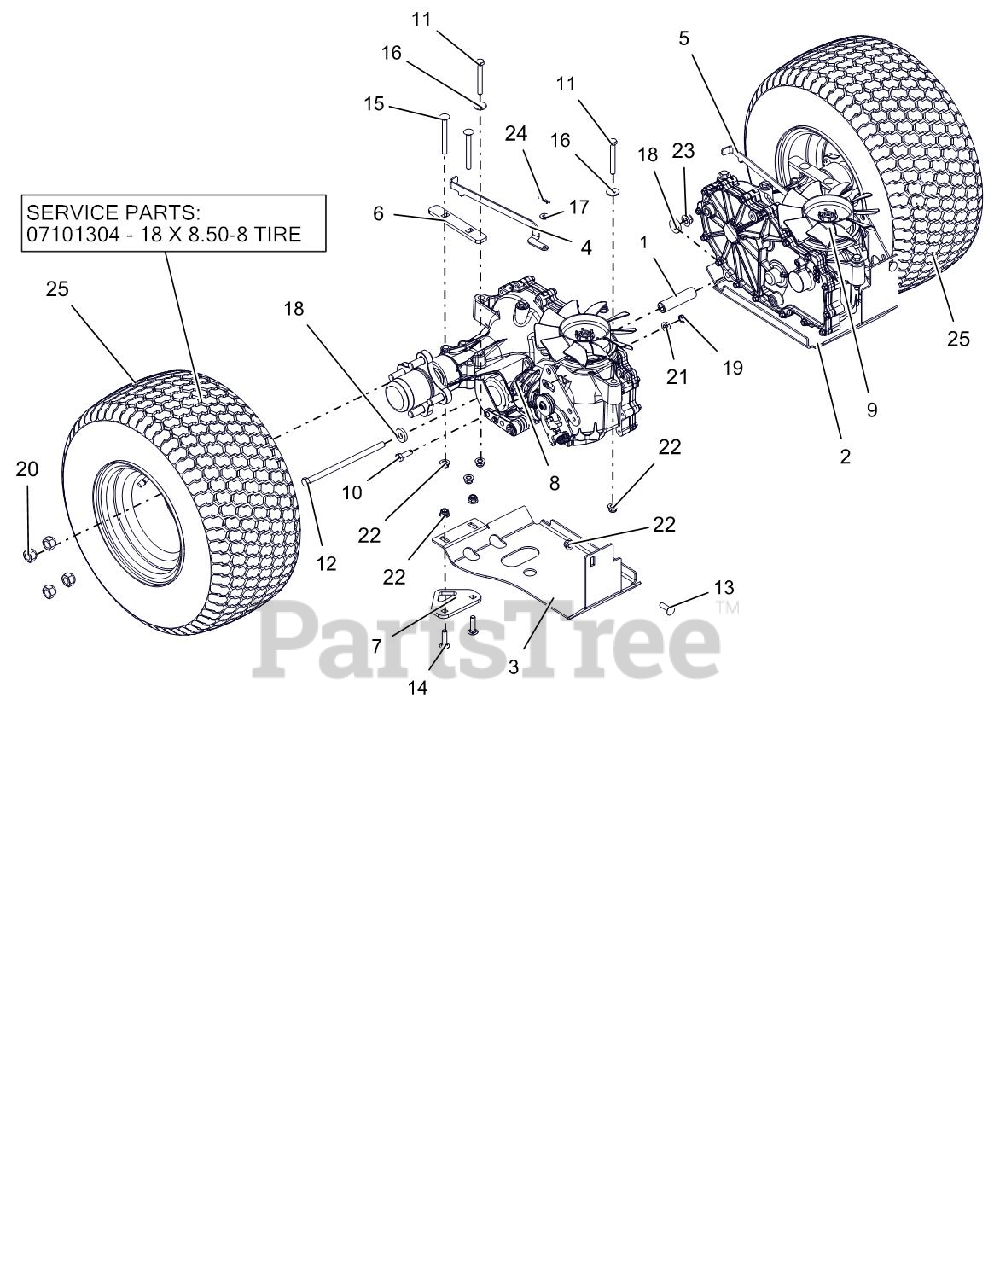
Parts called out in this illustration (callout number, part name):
1	SHAFT, CROSS BRACE
2	PLATE, TRANS SKID
3	PLATE, TRANS SKID
4	BRKT, LH DUMP VALVE
5	BRKT, RH DUMP VALVE
6	DOUBLER, TRANS MNT
7	BRKT, TIE DOWN LOOP
8	TRANSAXLE, RH - ZT31000
9	TRANSAXLE, LH - ZT3100
10	@BLT-HEX .31-18X1.00 GR5 YWZC
11	@BLT-HEX .31-18X2.50 GR5 YWZC
12	@BLT-HEX .38-16X7.00 GR5 YWZC
13	@BLT-RDHDSQNK .31-18X1.00 G5YZ
14	@BLT-RDHDSQNK .31-18X1.25 G5YZ
15	BLT-RDHDSQNK .31-18X3.00 G5YZ
16	@WSHR-FL-STL.38X.875X.083 YWZC
17	@WSHR-FL-STL.281X.62X.065 YWZC
18	WSHR-FL-STL .406X1.00X.188 YWZ
19	@NUT-LK-CTR-JAM .31-18 YWZC
20	WHEEL NUT .500-20 YZ
21	@NUT-SPNLK-FLG .312-18 YWZC
22	@NUT-LK-NYL-FLG .31-18 YWZC
23	@NUT-LK-NYL-FLG .38-16 YWZC
24	PIN-HAIR, ENDRIES #25 YWZC
25	ASM, WHL/TIRE 18X8.50-8
25	TIRE, 18 X 8.50-8
